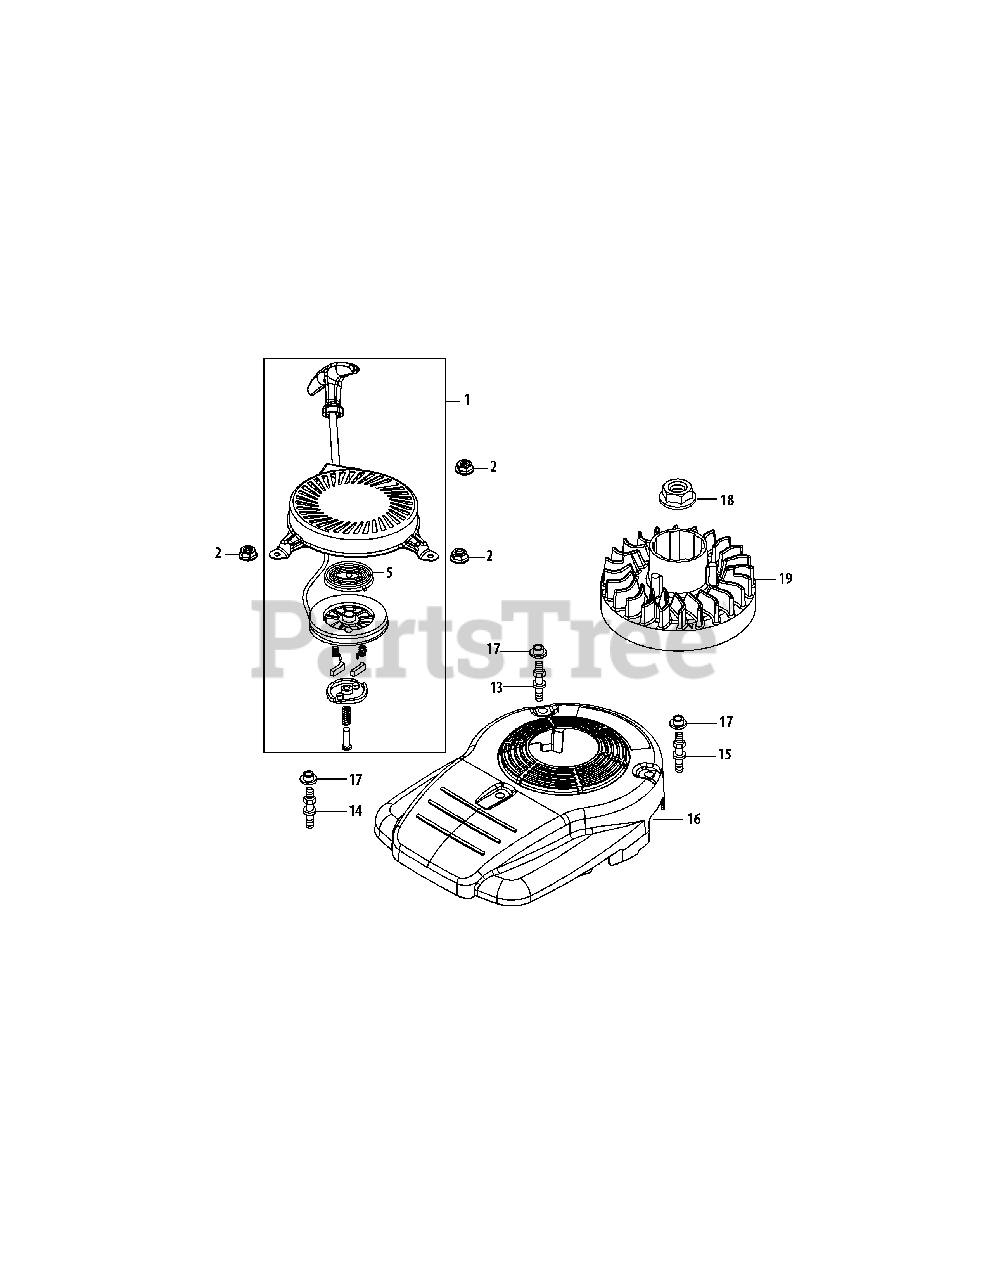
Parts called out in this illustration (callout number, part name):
1	Recoil Starter Assembly
2	Nut M6 X 10 Mm
5	Recoil Spring
13	Starter/Shroud Stud Black
14	Starter/Shroud Stud Front
15	Starter/Shroud Stud White
16	Engine Shroud (M0)
17	Engine Shroud Spacer
18	Flywheel Nut M14
19	Flywheel
